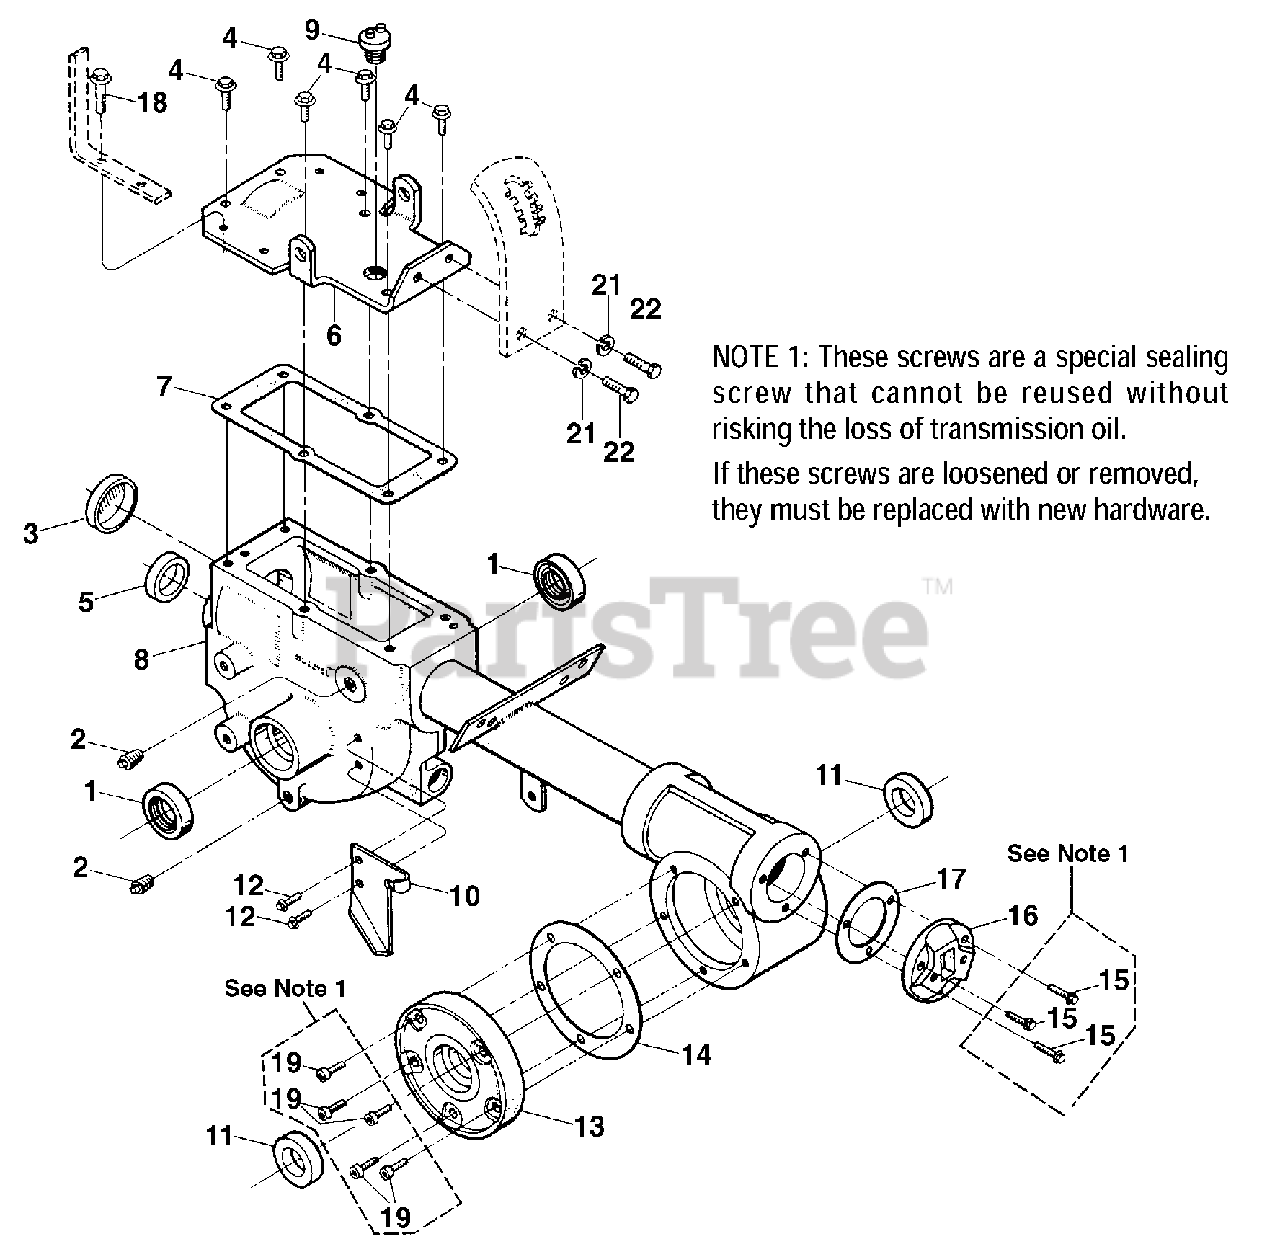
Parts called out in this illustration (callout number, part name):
1	Oil Seal (Double Lip), Wheel Shaft
2	Pipe Plug, 1/4,
3	Seal, Transmission Bore
4	Hex Flange Screw, 5/16-18 x 3/4
5	Oil Seal, Input Pinion Shaft
6	Transmission Cover (Incl. four Ref. 18 and two ea. Refs. 21 & 22)
7	Gasket, Transmission Top Cover
8	Transmission Case Assy. (Incl. Tube and Rear Housing)
10	Mounting Plate, Wheel Clutch Cable
11	Oil Seal, Tiller Shaft
12	Hex Flange Screw, 5/16-18 x 5/8
13	Tiller Housing Cover, left side
14	Gasket, Tiller Housing Cover, .010" (fits all covers)
15	Screw Kit: Incl. three 1/4-20 x 7/8 Self-Sealing Screws
16	Rear Bearing Cap
17	Gasket, Rear Bearing Cap, .010" Thick
18	Hex Flange Screw, 5/16-18 x 1
19	Screw Kit Incl. five 1/4-20 x 5/8 Self-Sealing Screws
21	Lockwasher, 3/8
22	Hex Hd. Screw, 3/8-16 x 3/4
